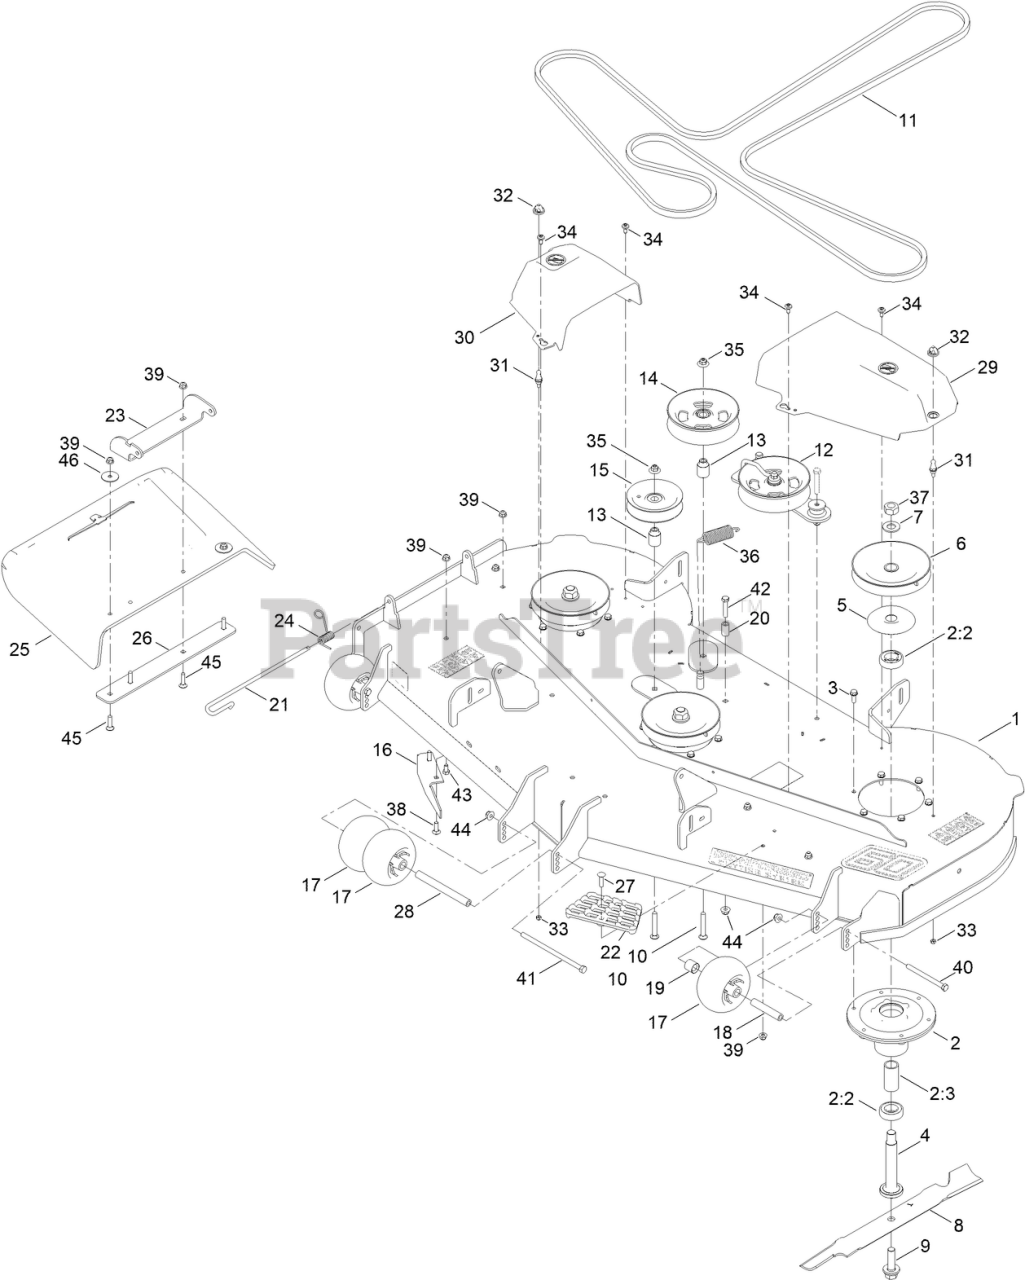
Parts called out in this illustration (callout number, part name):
1	ASM-DECK W/DECALS
2	SPINDLE ASM
2:2	BEARING-BALL
2:3	SPACER-BEARING
3	SCREW-TAPTITE
4	SHAFT-SPINDLE
5	SHIELD-BEARING
6	PULLEY
7	WASHER
8	BLADE-HI FLOW, 20.5 INCH
9	SCREW-BLADE
10	SCREW-CARR
11	BELT,V-B X 186.00"
12	IDLER ARM ASM
13	BUSHING-IDLER, FIXED
14	PULLEY-IDLER, FLAT
15	PULLEY-IDLER, FLAT
16	BAFFLE-CUTOFF
17	ROLLER-SCALP, ANTI
18	TUBE-SPANNER
19	SPACER-AXLE, REAR
20	SPACER-FENDER
21	PIN-CHUTE
22	STEP-DECK
23	BRACKET-DEFLECTOR, UPPER
24	SPRING-TORSION
25	DEFLECTOR - MOLDED
26	PLATE-DEFLECTOR
27	BOLT-CARRIAGE
28	SPACER-WHEEL
29	COVER-BELT, LH
30	COVER-BELT, RH
31	STUD-BALL
32	GROMMET-BALL
33	NUT-LOCK
34	SCREW-SHOULDER
35	NUT-FLANGE, NI
36	SPRING - EXTENSION
37	NUT-HEX
38	SCREW-CARR
39	NUT-HF, NI
40	SCREW-HH
41	SCREW-HH
42	SCREW-HH
43	SCREW-HH
44	NUT-HF, NI
45	SCREW-CARR
46	WASHER-FLAT
